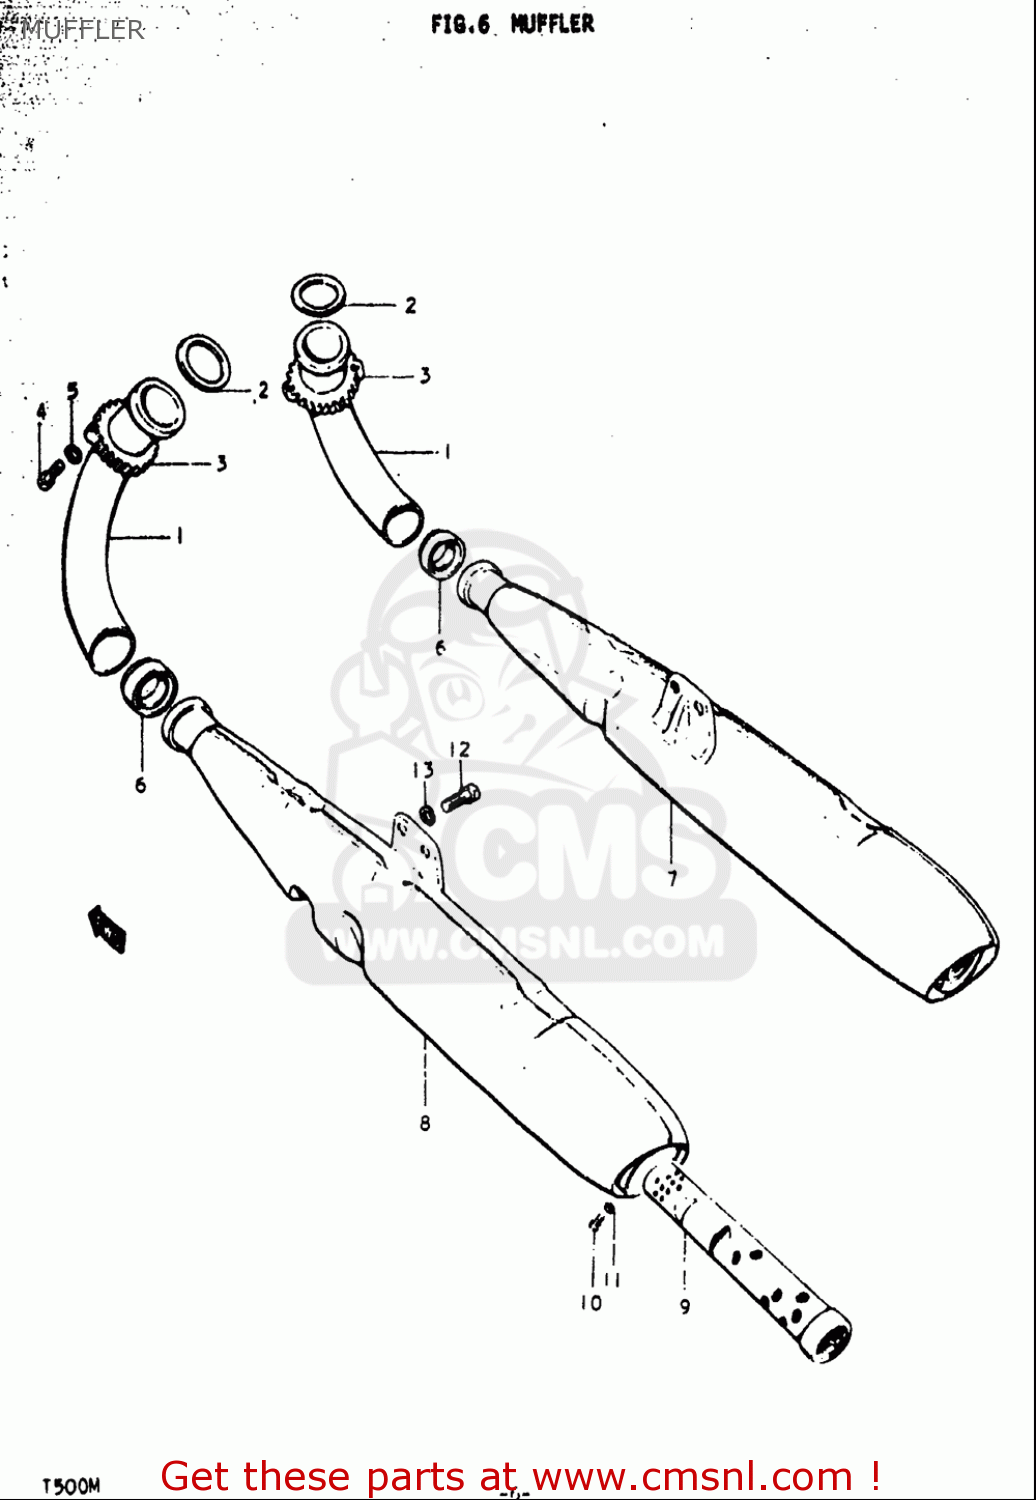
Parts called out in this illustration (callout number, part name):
1	PIPE,EXHAUST
2	GASKET,EXHAUST PIPE (NAS)
4	BOLT
5	WASHER,LOCK
6	CONNECTOR,MUFFLER
9	PIPE,BAFFLE
10	SCREW(5X6)
11	WASHER,LOCK
12	BOLT
13	WASHER,LOCK
